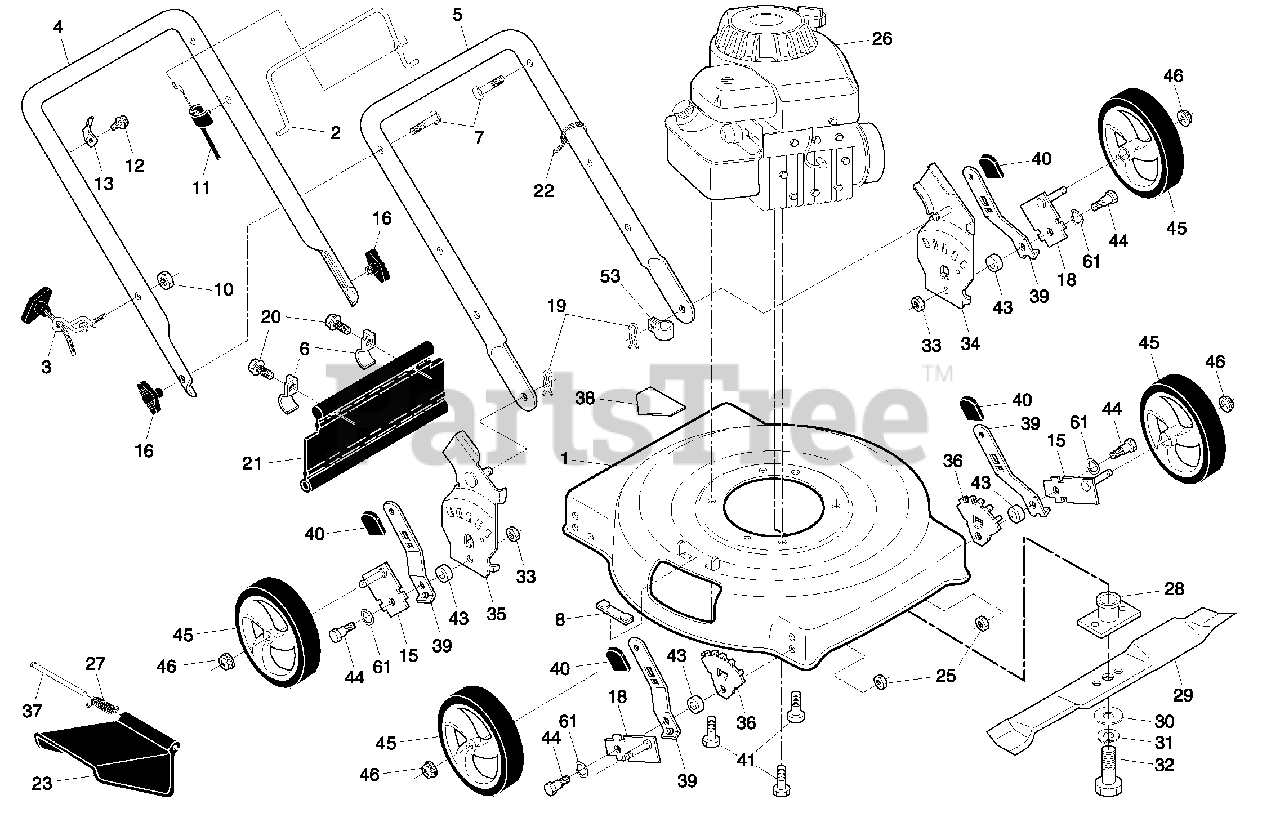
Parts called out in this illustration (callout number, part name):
1	Kit, Housing
2	Control Bar
3	Rope Guide
4	Upper Handle
5	Lower Handle
6	Bracket, Rear Skirt
7	Handle Bolt 5/16-18
8	Clip, Closeout
10	Locknut, Hex 1/4-20
11	Engine Zone Control Cable
12	Screw, Hex Head, Threaded, Rolled #10-24 x 1/2
13	Up-Stop Bracket
15	Axle Arm Assembly, Left Front & Right Rear
16	Handle Knob
18	Axle Arm Assembly, Right Front & Left Rear
19	Hairpin Cotter
20	Screw, Tapping, Hex Washer Head #10-24
21	Rear Skirt
22	Wire Tie
23	Discharge Guard
25	Nut, Hex, Flangelock 5/16-18
27	Torsion Spring
28	Blade Adapter
29	22" Blade
30	Hardened Washer
31	Helical Lockwasher 3/8
32	Screw, Hex Head, Grade 8, 3/8-24 x 1-3/8
33	Nut, Hex, Flangelock 5/16-18
34	Wheel Bracket Support (Left)
35	Wheel Bracket Support (Right)
36	Wheel Bracket Adjuster
37	Hinge Rod
38	Danger Decal
39	Selector Spring
40	Selector Knob
41	Screw, Hex Head, Threaded, Rolled 3/8-16 x 1
43	Spacer
44	Shoulder Bolt 5/16-18 x .33
45	Wheel & Tire Assembly
46	Nut, Hex, Flangelock 3/8-16
53	Clip, Cable
61	Washer, Curved, Cylindrical
61	Operator's Manual, English
61	Operator's Manual, French
61	Repair Parts Manual
